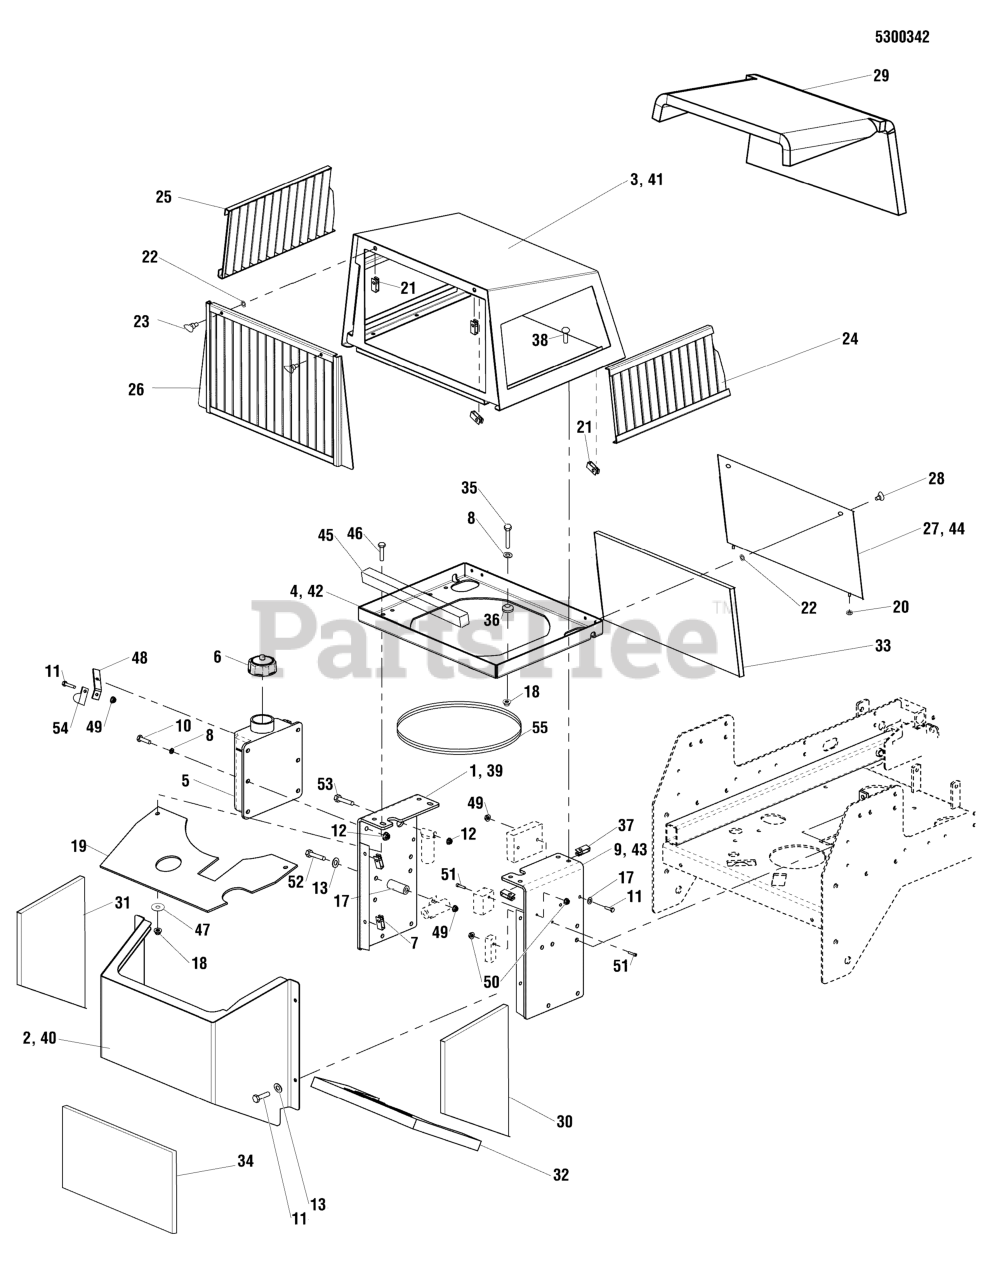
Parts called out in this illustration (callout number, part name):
1	WELD, RADIATOR MT, LH - RED MODEL
2	WELD, FRAME, HOOD, REAR - RED MODEL
3	WELD, FRAME, HOOD, YANMAR - RED MODEL
4	WELD, MOUNT, RADIATOR - RED MODEL
5	TANK, HYDRAULIC, ASSEMBLY
6	CAP, HYDRAULIC
7	BODY CLIP, 1/4-20 X 1/2"
8	WASHER, 5/16" SAE
9	WELD, MOUNT, RADIATOR, RH - RED MODEL
10	BOLT, 5/16-18 X 1" GD5 YZ
11	BOLT, 1/4-20 X 1" GD5 CZ
12	NUT, 5/16-18 HEX NYLOCK FLANGE
13	WASHER, 1/4 SAE
14	HOSE, COOLANT - YANMAR DIESEL
15	HOSE, COOLANT - Z - YANMAR DIESEL
16	CLAMP, SS HOSE, 1-3/4"
17	SPACER, .20 X .38 X 1.25
18	NUT, 3/8-16 HEX NYLOCK FLANGE
19	FLAP, RUBBER, YANMAR
20	GROMMET, 3/8"
21	RECEPTACLE, #12 WING HEAD SCREW
22	RETAINER, #12 WING HEAD SCREW
23	SCREW, WING HEAD
24	SCREEN, HOOD, TOP, RH
25	SCREEN, HOOD, TOP, LH
26	PRESCREEN RADIATOR, YANMAR DIESEL ENGINE
27	WELD, HOOD, FRONT - RED MODEL
28	SCREW, WING HEAD
29	FOAM, SOUND BAFFLE, TOP, YANMAR
30	FOAM, SOUND BAFFLE, REAR, YANMAR
31	FOAM, SOUND BAFFLE, REAR, YANMAR
32	FOAM, SOUND BAFFLE, REAR, YANMAR
33	FOAM, SOUND BAFFLE, YANMAR
34	FOAM, SOUND BAFFLE,
35	BOLT, 5/16-18 X 4.25" GD5 YZ
36	ISO MOUNT, YANMAR DIESEL, RADIATOR
37	U-NUT, MULTI-THREADED, 5/16-18
38	SCREW, 5/16-18 X 1-1/4" GD5
39	WELD, RADIATOR MT, LH - ORANGE MODEL
40	WELD, FRAME, HOOD, REAR - ORANGE MODEL
41	WELD, FRAME, HOOD, YANMAR - ORANGE MODEL
42	WELD, MOUNT, RADIATOR - ORANGE MODEL
43	WELD, MOUNT, RADIATOR, RH - ORANGE MODEL
44	WELD, HOOD, FRONT - ORANGE MODEL
45	FOAM ,3/4" THICK X 1" WIDE - 12.25"
46	BOLT, 3/8-16 X 1-1/4" GD5 CZ
47	WASHER, 3/8" FENDER
48	BRACKET, HOSE - BLK
49	NUT, 1/4-20 HEX NYLOCK FLANGE
50	NUT, #10-24 HEX NYLON LOCK
51	SCREW, #10-24 X 3/4" ROUND PHILLIPS
52	BOLT, 1/4-20 X 2", GD5
53	BOLT, 5/16-18 X 2-3/4, GD 5, YZ
54	CLAMP, VINYL INSULATED
55	SEAL, WIPER, CLIP ON 43.50
